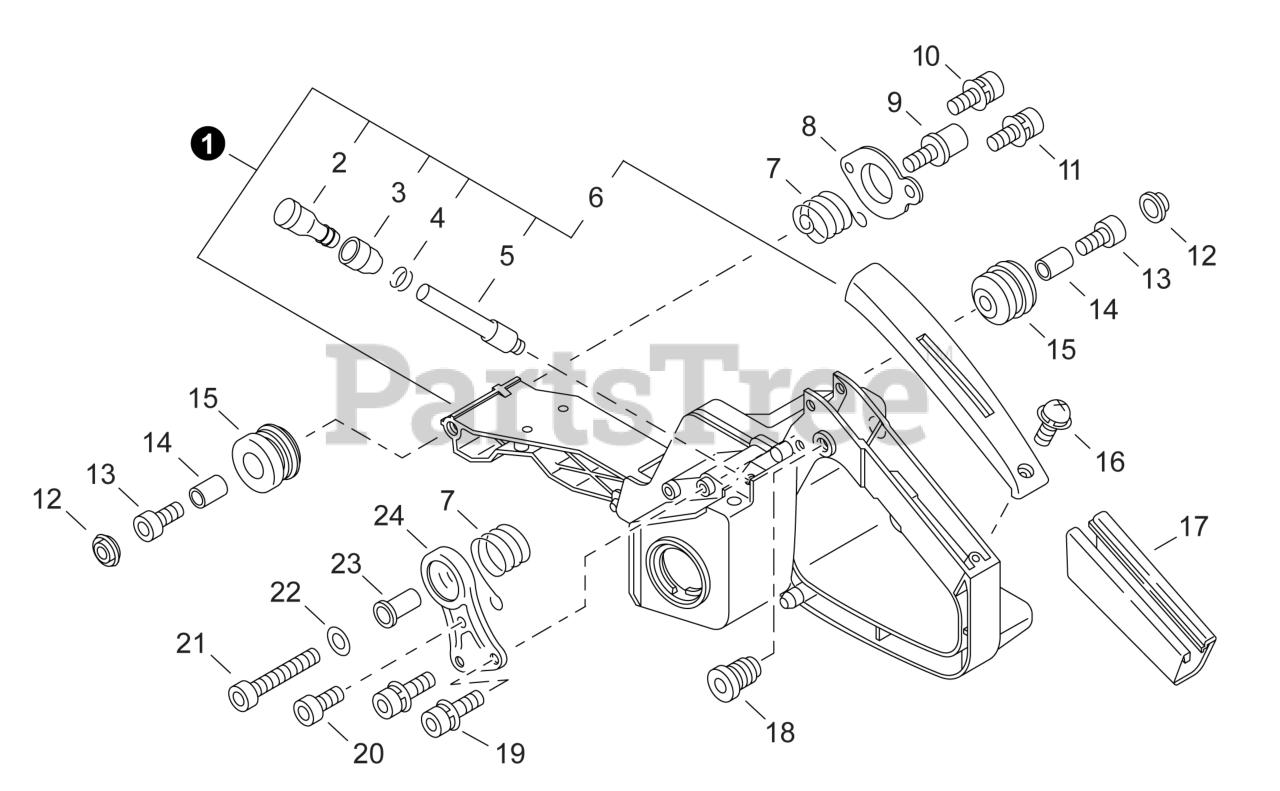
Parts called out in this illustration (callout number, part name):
1	HANDLE ASSY, REAR
2	VENT ASSY
3	HOLDER, VENT
4	CLIP Ø6.5 MM
5	PIPE, VENT
6	COVER, HANDLE
7	SPRING, COMPRESSION
8	PLATE, EYE
10	BOLT 4×8
11	BOLT 5×14
12	CAP, CUSHION
13	BOLT 5×25
14	COLLAR 5
15	CUSHION
16	SCREW 4×14
17	GRIP, HANDLE
19	BOLT 5×14
20	BOLT 5×8
21	SCREW - 5×35
22	WASHER 5
23	COLLAR 5
24	BRACKET, CUSHION
